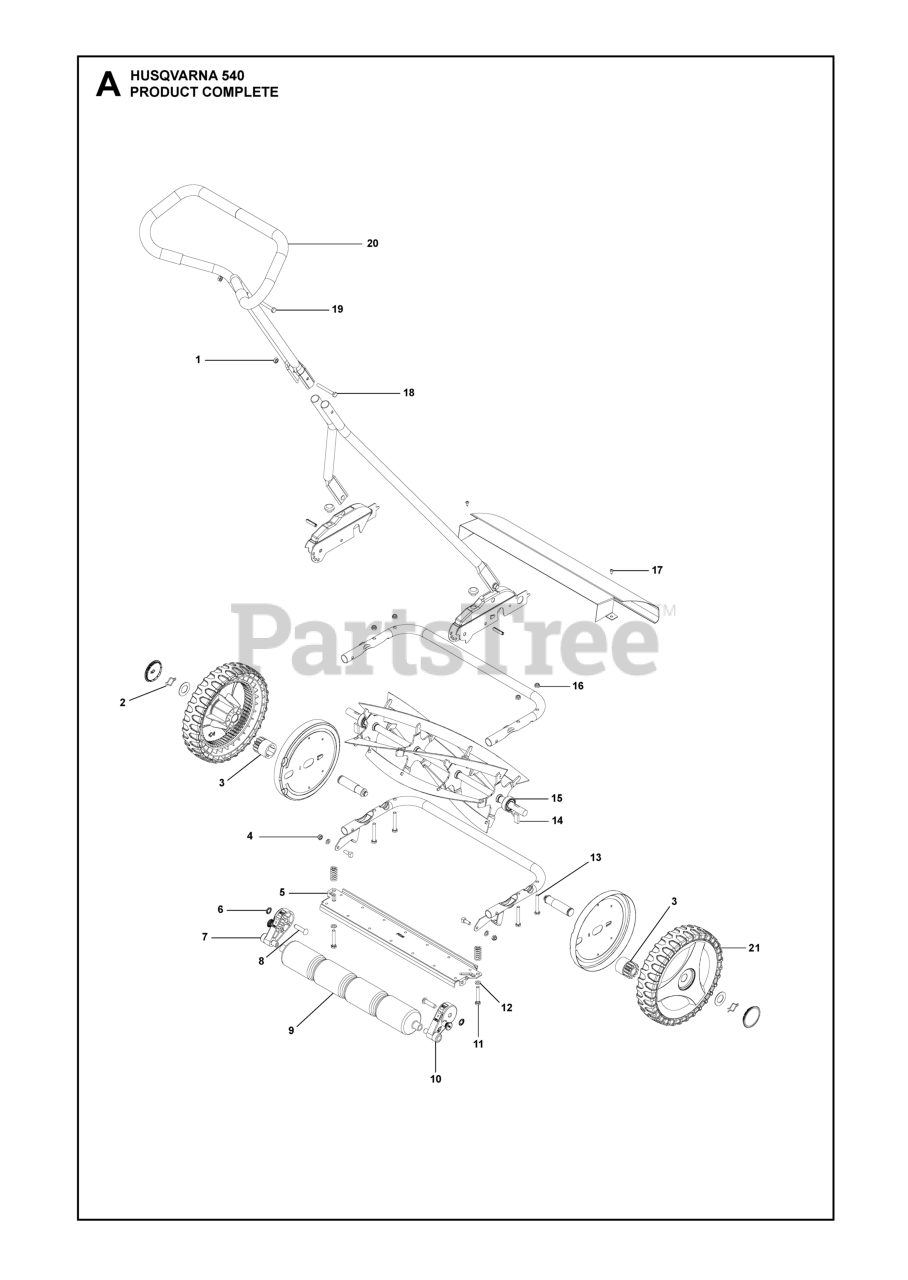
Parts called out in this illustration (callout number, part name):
1	LOCKNUT M6
3	PINION SET
4	LOCKNUT M6
6	LOCKING WASHER
7	HOLDER
10	HOLDER
16	LOCKNUT M6
18	SCREW M6X50
21	WHEEL ASSY
21	WHEEL
